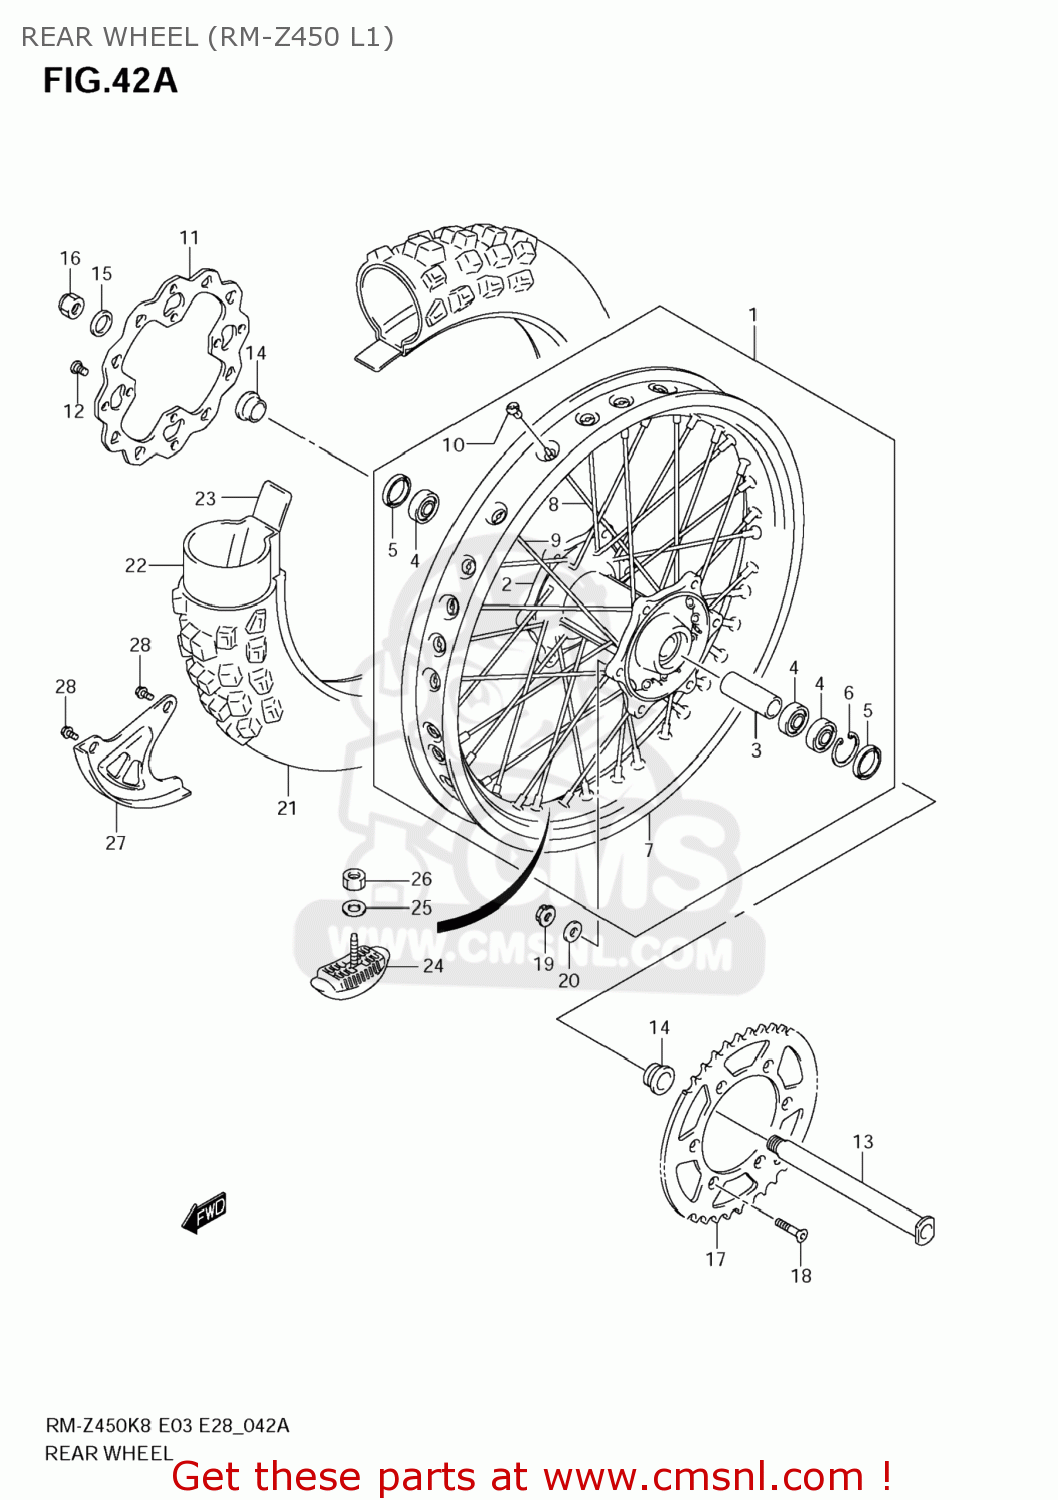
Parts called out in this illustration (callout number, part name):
1	WHEEL ASSY,RR
2	HUB,RR
3	SPACER,RR HUB BEARING
4	BEARING(25X42X9)
5	SEAL,OIL(32X43X7)
6	CIRCLIP
7	RIM,RR WHEEL(19X2.15 AL)(WHT)
8	SPOKE,RR WHEEL INNER
9	SPOKE,RR WHEEL OUTER
10	NIPPLE,RR WHEEL
11	DISC,RR BRAKE
12	SCREW(8X15)
13	AXLE,RR
14	SPACER,RR AXLE
15	WASHER(22X35X2)
16	NUT
17	SPROCKET,RR(NT:50)
18	BOLT(8X28)
19	NUT
20	WASHER(8.5X16X1.2)
21	TIRE,RR(110/90 19)
22	TUBE ASSY,WHEEL INNER
23	PROTECTOR,WHL INR TUBE
24	STOPPER,BEAD(2.15)
25	WASHER
26	NUT
27	COVER,RR DISC
28	BOLT(6X12)
